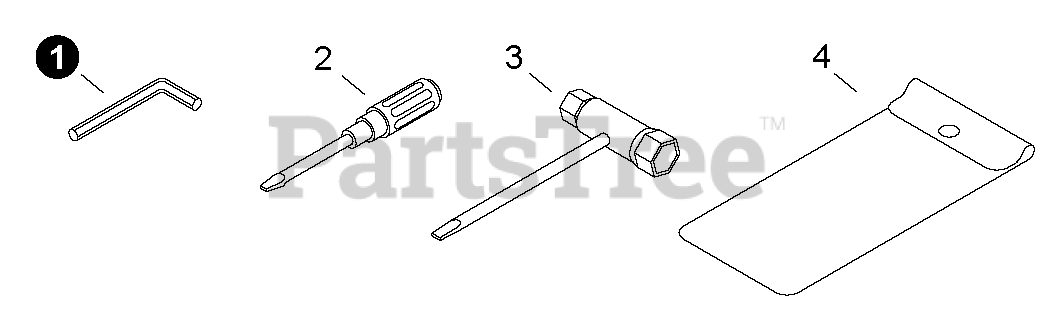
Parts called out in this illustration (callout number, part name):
1	HEX KEY - 4mm
2	SCREWDRIVER
3	T-WRENCH - 13X19mm
4	BAG, TOOL
